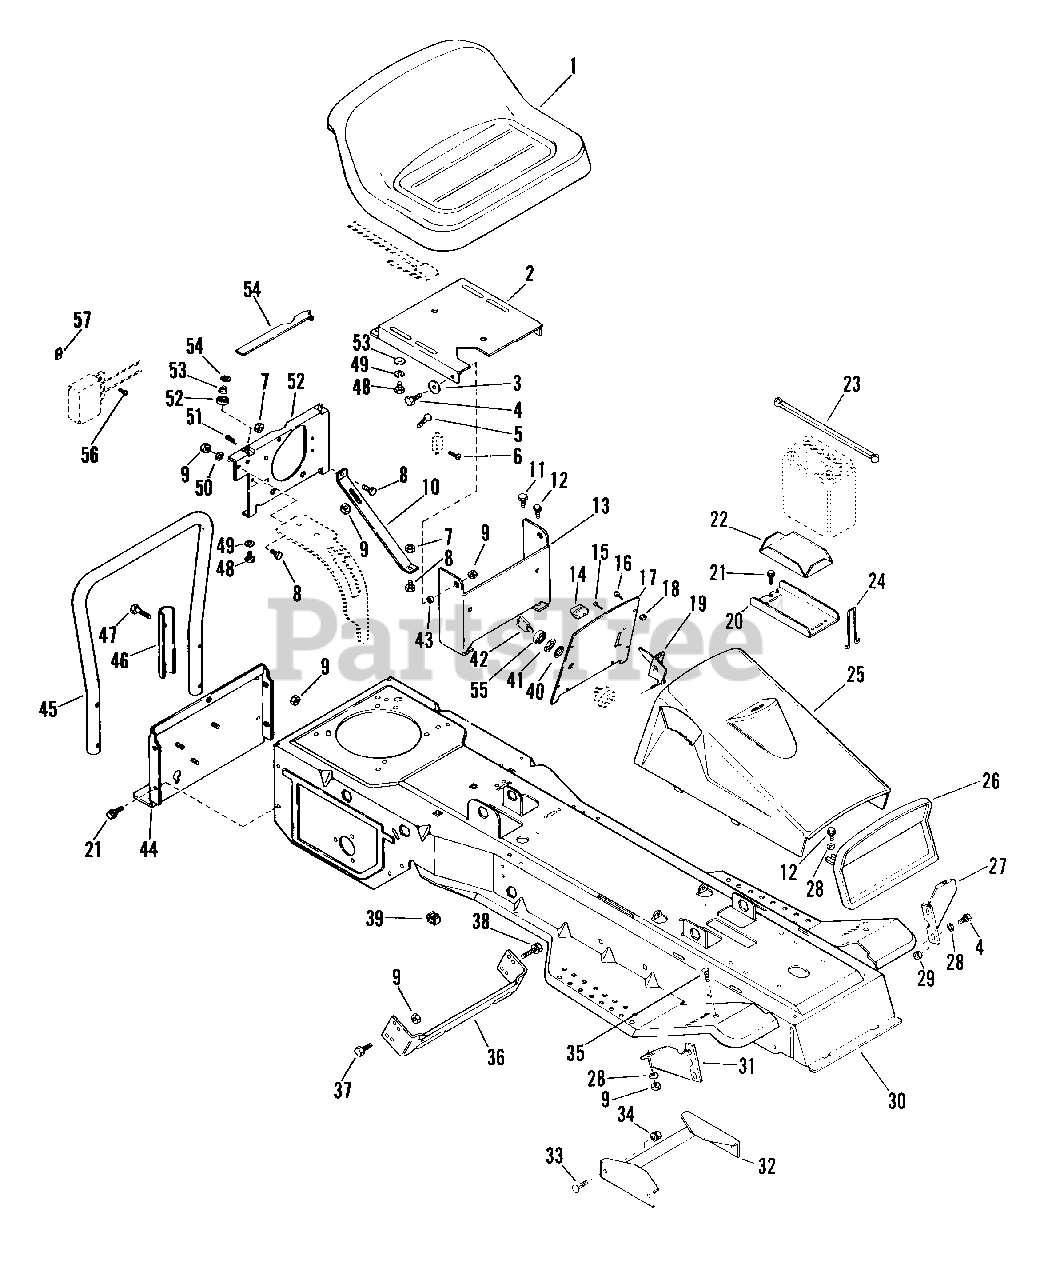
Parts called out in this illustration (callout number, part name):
1	SEAT W/SWITCH REPLACEMENT PACK
2	SEAT BRACKET
3	WSHR-FL-STL .344X1.125X.063PL
4	BLT-HEX .31-18X.75 PL GR2
5	BLT-RDHDSQNK .312-18X.62 PL
6	SCR-MCH 10-24X.62 SLRH PL
7	NUT-LK-CTR .250-20 PL
8	BLT-HEX .25-20X.50 PL GR2
9	NUT-LK .312-18 GR A PL
11	BLT-HEX .31-18X.50 PL GR2
12	SCR-TAP .250-20X.50 HXSLHDPL
13	SEAT PIVOT BRACKET
15	SCR-TAP 10-24X.375 CRPH 1A
16	SCR-TAP 10-12X.50 CRPH PL A BL
17	DASH PANEL-RM
18	PLASTIC GROMMET
19	THROTTLE CONTROL
20	BATTERY TRAY
21	SCR-TAP .312-18X.50 HWH PL TR
22	RUBBER PAD
23	BATTERY STRAP
24	HOOK
26	GRILLE INSERT & SHELL ASSEMBLY
27	L H FENDER BRACE
28	WSHR-FL-STL .323X.625X.062 PL
29	NUT-LK-TWIN .312-18 PL
30	FRAME WITH DECALS
31	RH FENDER BRACE
32	FRAME BRACE
33	BLT-RDHDSQNK .312-18X.62SHTPL
34	NUT-FLG. .312-18 PL
35	BLT-RDHDSQNK .31-18X.75 GR5 PL
36	FRAME BRACE
37	BLT-HEX .31-18X.63 PL GR 2
38	SCR-TAP .312-18X1.50 HWH PL TR
39	NUT RETNR .25-20
40	WSHR-LK-INT .625X.045 PL
41	NUT-PANEL .625-32 GRECO
42	KEY SET
43	SPACER BUSHING .5 X .32 X .163
44	BACK COVER
45	TUBE
46	BRACE
47	BLT-HEX .31-18X1.50 PL GR2
48	BLT-HEX .31-18X.75 PL GR5
49	WSHR-LK .312X.097 PL HVY
50	WSHR-LK-INT .313X.030 PL
51	PIN-HAIR INT .08X.18X1.18
52	SEAT LEG
53	WSHR-FL-STL .38X.875X.083 PL
54	SEAT HOLD DOWN
55	CAP - IGNITION SWITCH
56	SCR-MCH 10-24X.38 SLTOR PAN PL
57	NUT-KEPS 10-24 PL
